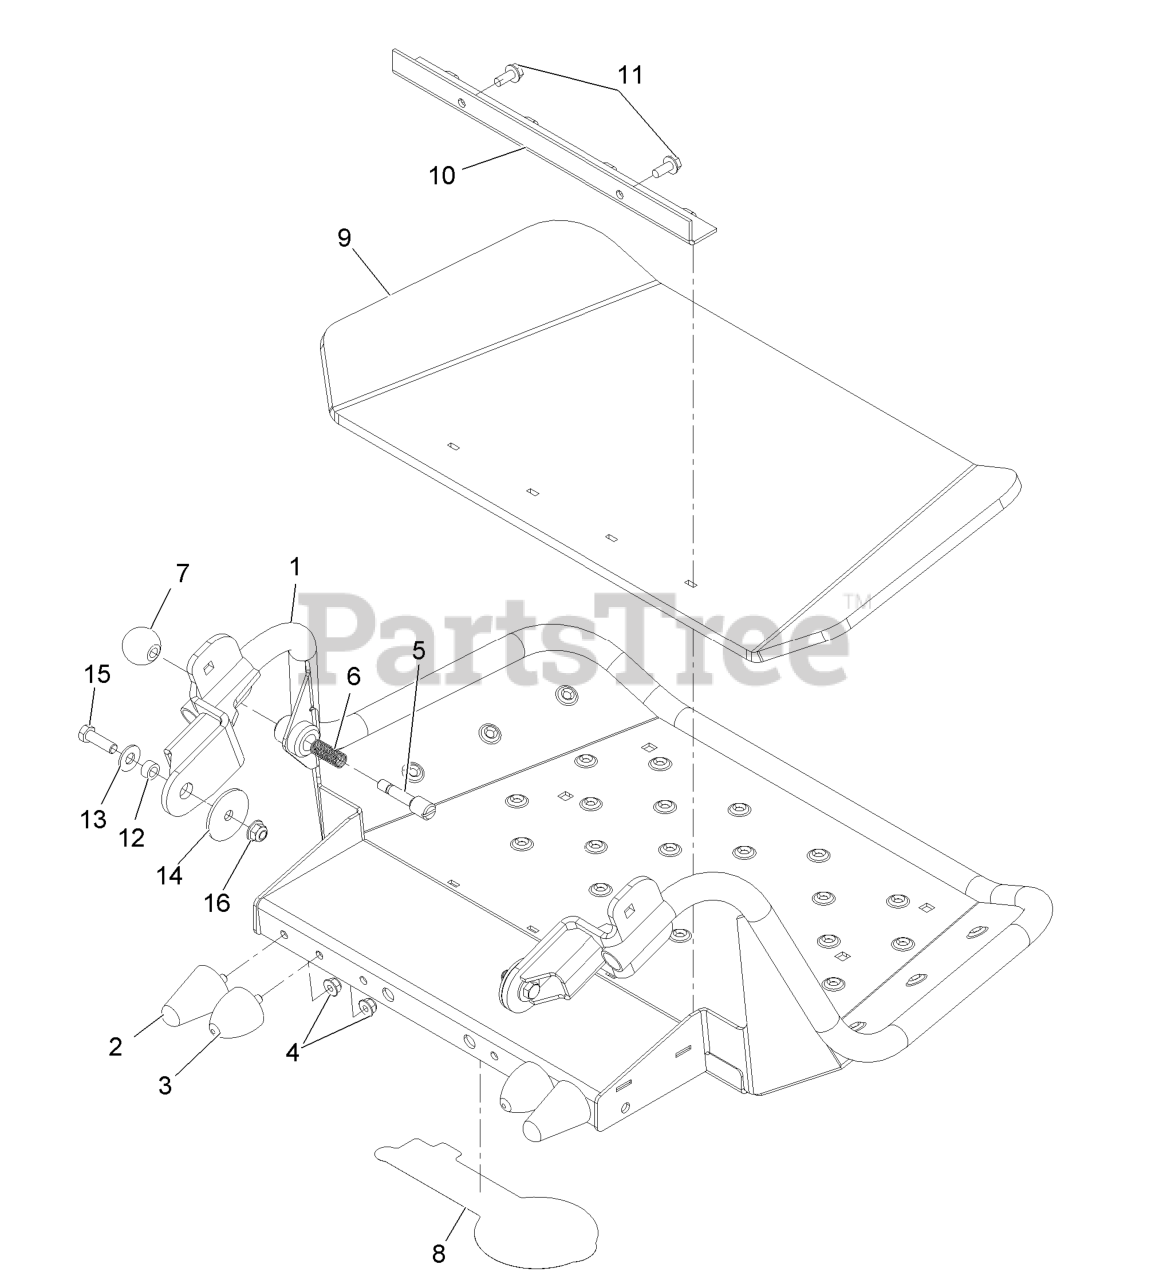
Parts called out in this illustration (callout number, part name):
2	BUMPER-RUBBER
3	BUMPER-RUBBER
4	NUT-HF, NI
5	PIN-LATCH
7	KNOB-BALL
8	DECAL, EXMARK LOGO
10	CLAMP-SHIELD
11	SCREW-THD ROLL, HWH
12	SPACER
13	WASHER-FLAT
14	WASHER-FLAT
15	SCREW-HH
16	NUT-HF, NI
